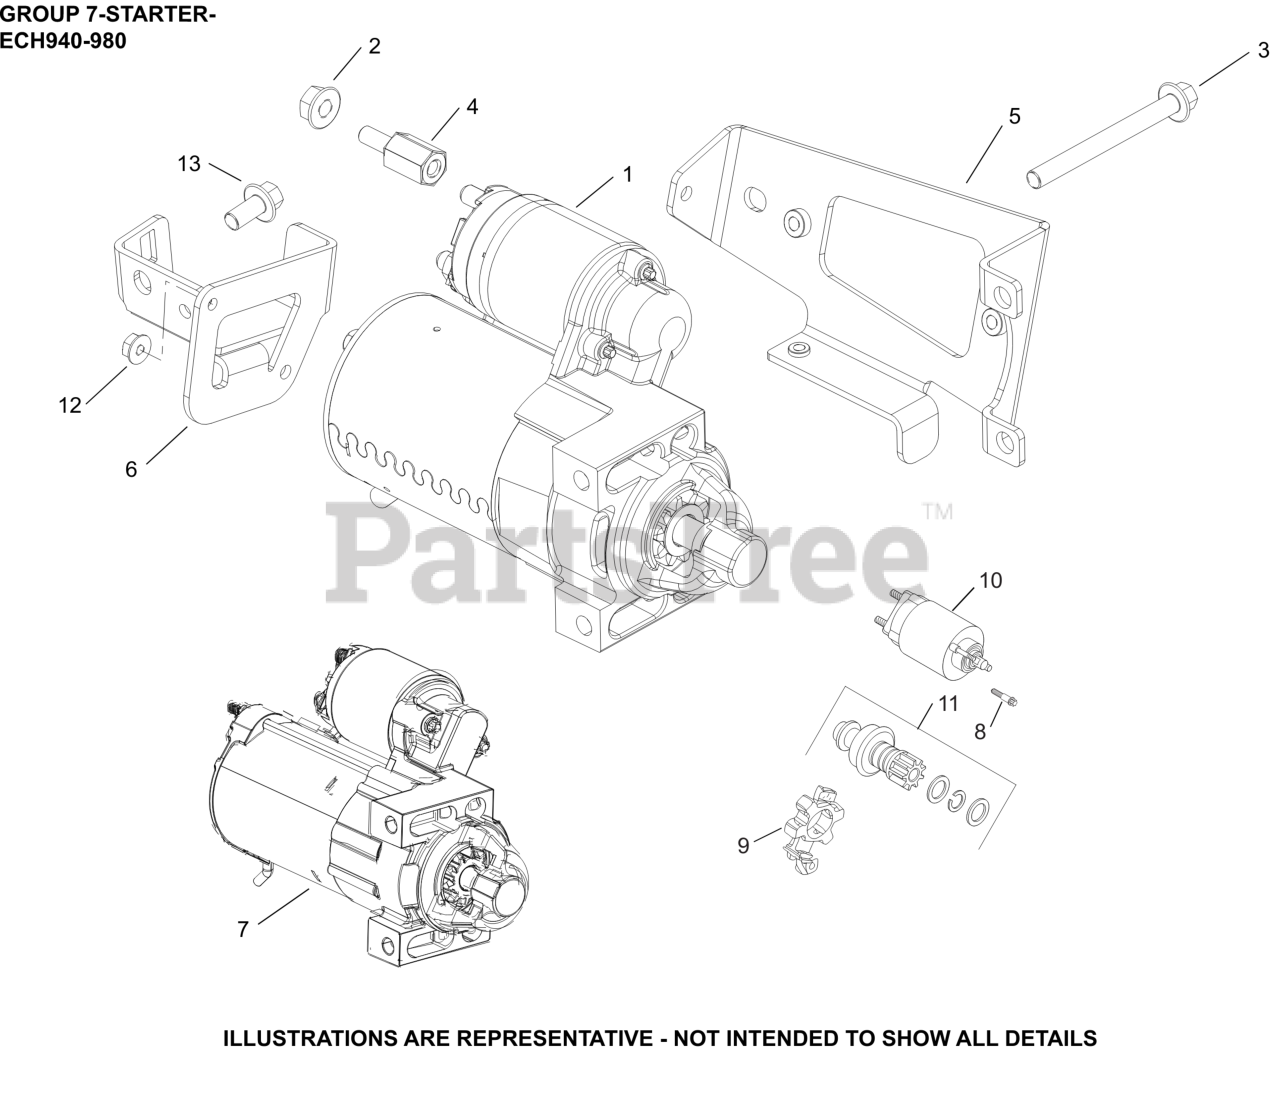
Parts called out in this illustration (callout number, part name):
1	STARTER, SOLENOID SHIFT
2	NUT, FLG M8X1.25
3	SCREW, FLG M8X1.25X80
